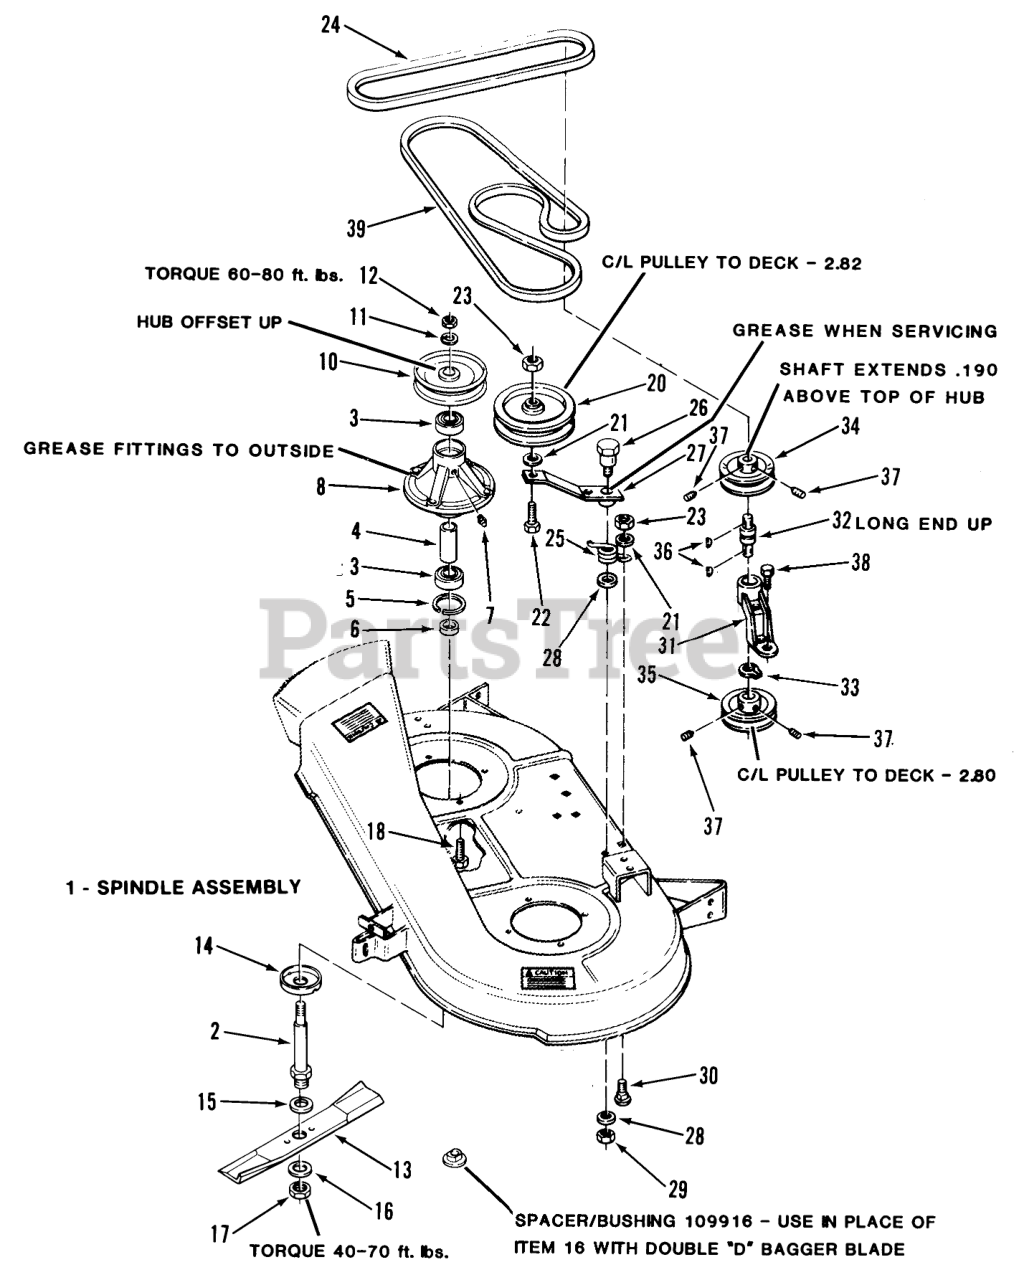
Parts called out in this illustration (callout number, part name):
1	Spindle Assembly (Includes Items 2 to 8, 14)
2	SHAFT SPINDLE
3	BEARING-BALL
5	Ring-Snap
6	SPACER-BLADE
7	Fitting-Grease
8	HOUSING SPINDLE
10	PULLEY BLADE
11	Lockwasher
12	Nut
13	ASSY BLADE KIT
14	CUP-SPINDLE
15	Washer
16	SpeciaI Washer
17	Nut
18	Bolt
20	Idler Pulley
21	Washer
22	Bolt
23	Nut
24	V-BELT
25	SPRING-TORSION
26	BOLT-SHOULDER
27	Idler Arm
28	WASHER
29	NUT-JAM(7/16-14)
30	Bolt
31	HOUSING DRIVE BRG R
32	BEARING-INT SHAFT
33	Snap Ring
34	PULLEY
35	PULLEY-SPLIT
36	KEY-WOODRUFF
37	Set Screw
38	Bolt
39	BELT-V MOWER
